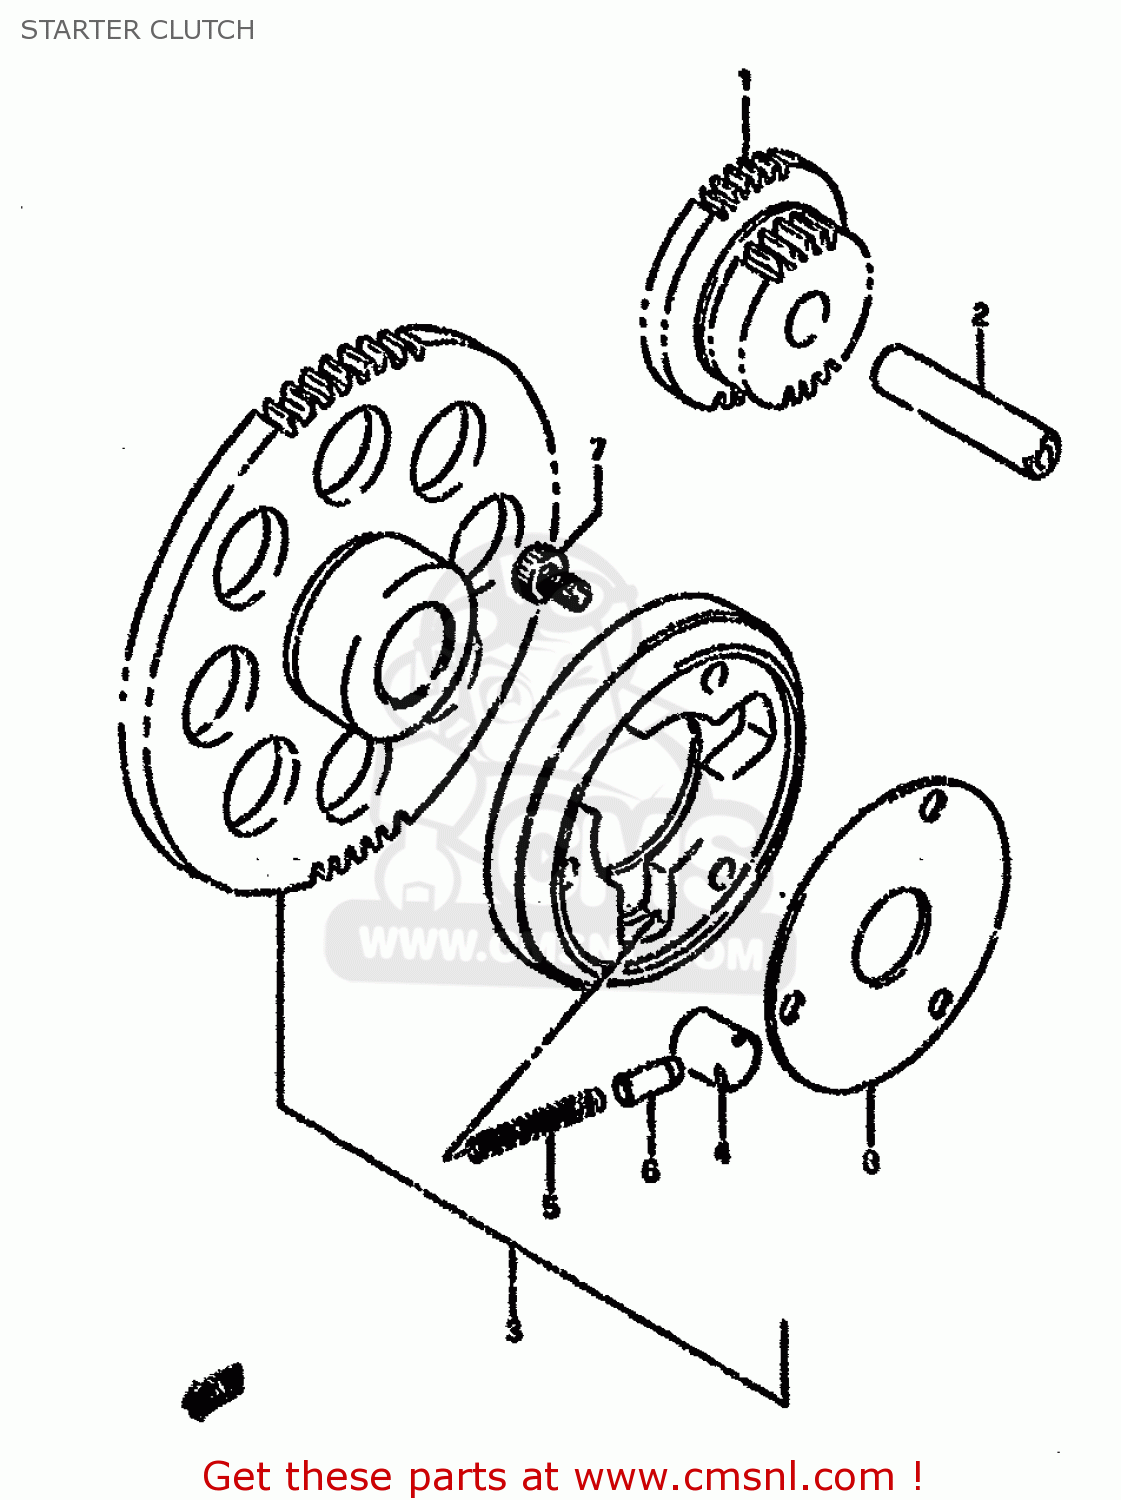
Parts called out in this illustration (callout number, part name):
1	GEAR,STARTER IDLE
2	PIN(7.4X13X56)
3	CLUTCH SET,STARTER
4	ROLLER(15X13)
5	SPRING
6	PIECE,PUSH
7	BOLT
8	SHIM,STARTER CLUTCH HUB
